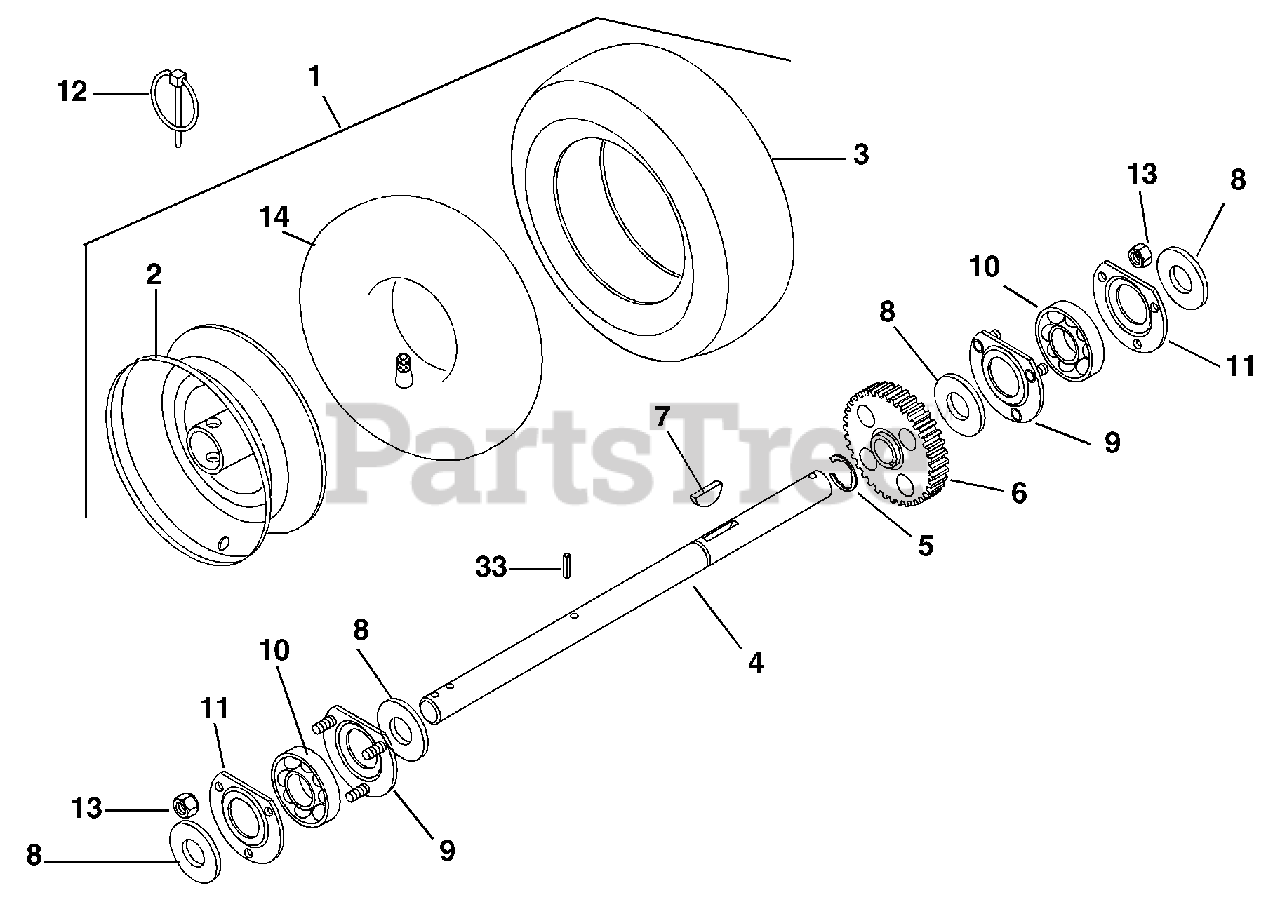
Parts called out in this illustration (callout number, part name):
1	TIRE/WHEEL ASSEMBLY 16X6.50-8
2	WHL 6.50X8
3	TIRE 16X6.50-8 SNO-HOG TREAD
4	SHAFT, AXLE
5	RG-RTNG-EXT. .875X.050
6	GEAR, SPUR
7	KEY-WDRF .25X.875X.375 SAE A
8	WSHR-FL-STL .880X1.250X.062YWZ
9	BEARING FLANGE
10	BRG-BALL .876 X 1.750 X .50
11	BEARING FLANGE
12	PIN-LOK .31X1.75
13	@NUT-LK-CTR .25-20 YWZC
14	TUBE
33	PIN-ROLL .188X1.50
